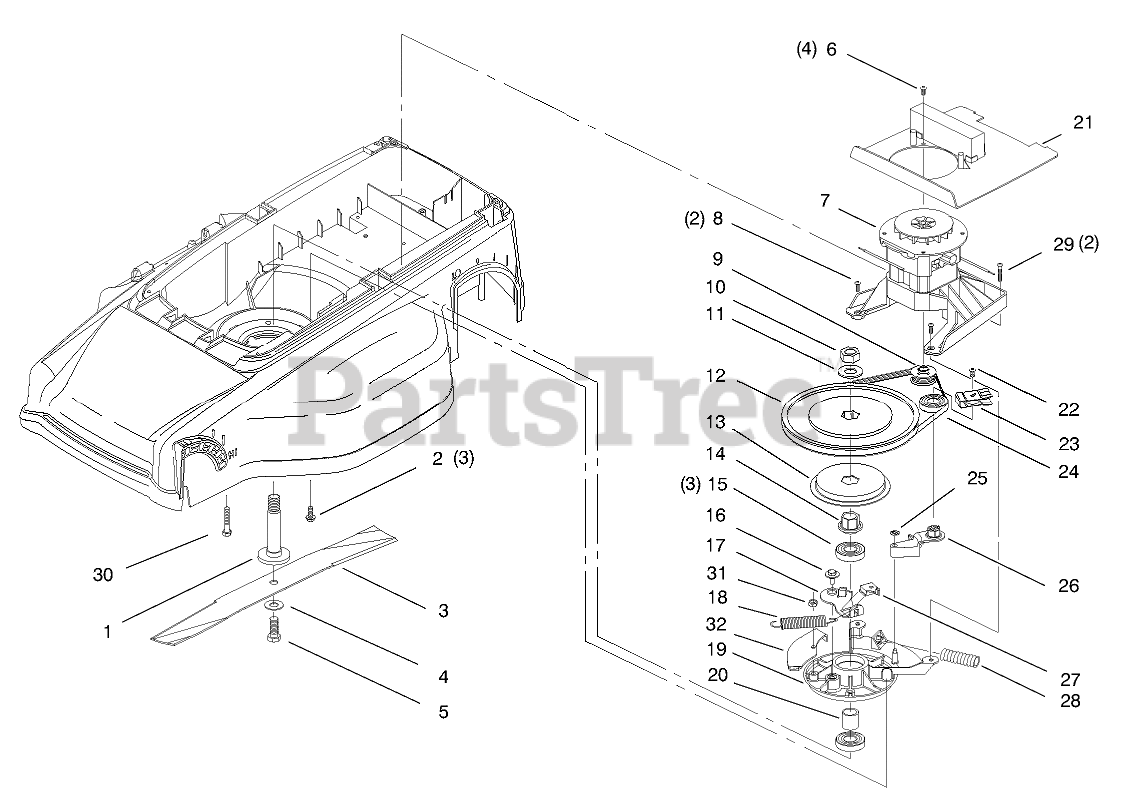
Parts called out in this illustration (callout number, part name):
1	SHAFT - SPINDLE
2	SCREW-HWH, THREAD ROLL
3	Blade
4	WASHER-BELLEVILLE
5	SCREW-HH
6	SCREW-PPH
7	MOTOR ASM
8	SCREW-PPHTF
9	PULLEY - MOTOR
10	NUT-HEX
11	WASHER-FLAT
12	PULLEY - DRIVEN
13	DRUM - BRAKE
14	HUB - PULLEY
15	Bearing-Ball
16	SCREW-SHOULDER
17	LEVER ASM-BRAKE
18	SPRING - BRAKE SWITCH
19	SPINDLE
20	SPACER - BEARING
21	BAFFLE ASM
22	SCREW
23	GUIDE - BELT
24	BELT - POLY V
25	PUSHNUT-TINNERMAN
26	IDLER ARM
27	MOUNT - CABLE
28	SPRING
29	SCREW - PPH
30	SCREW-HWH
31	NUT-LOCK, NI
32	BRACKET - SPRING
